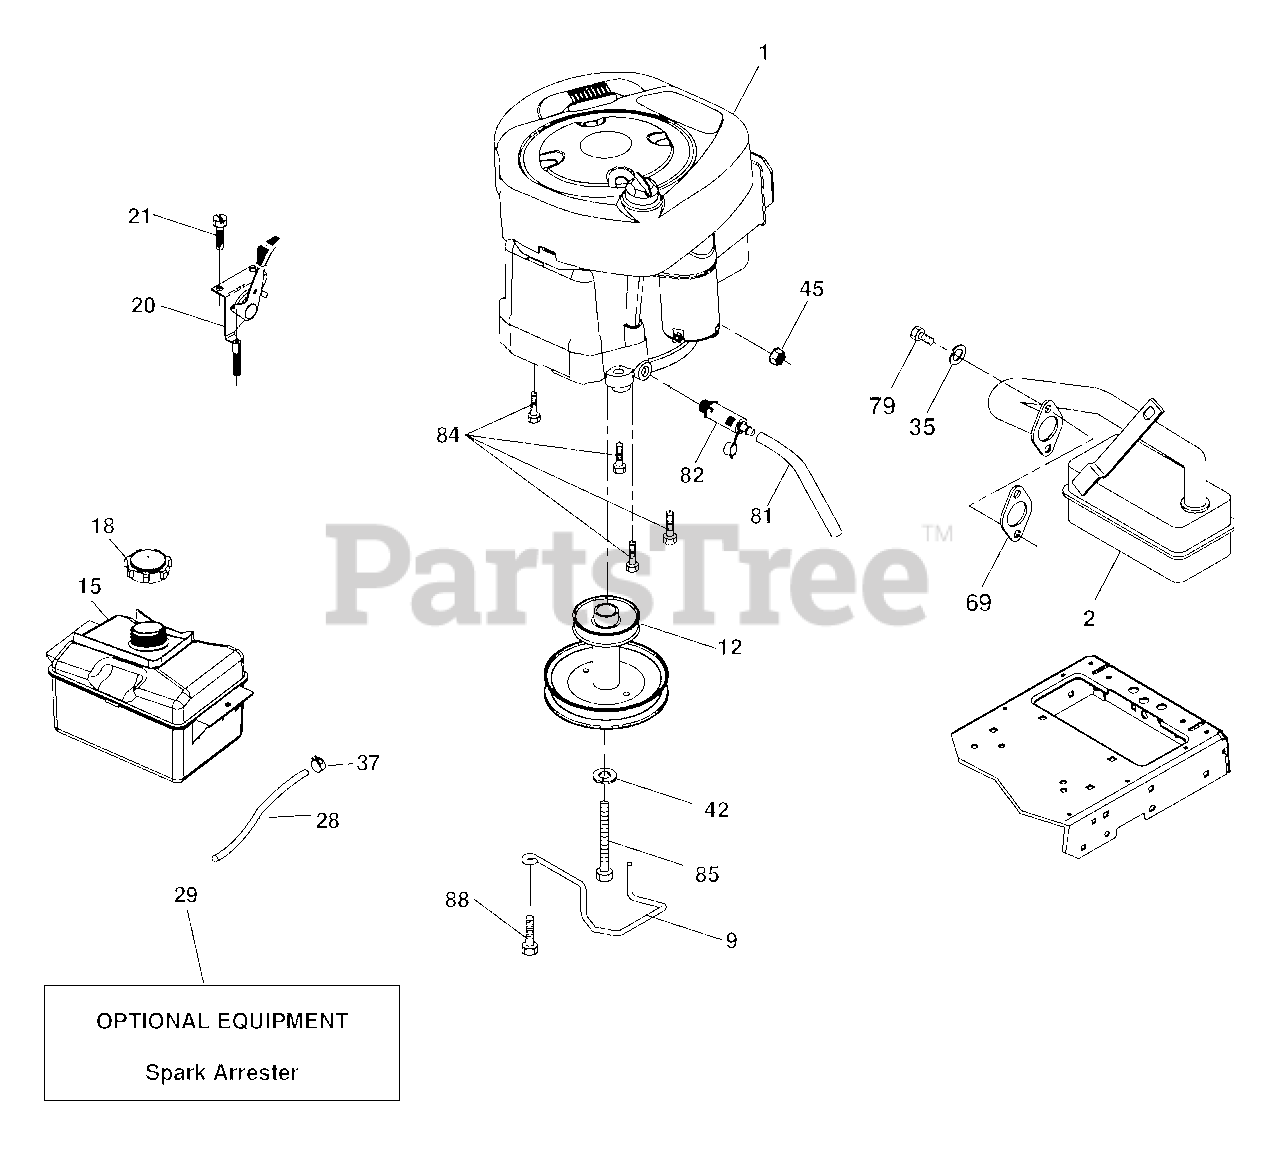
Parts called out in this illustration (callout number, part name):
2	Muffler
9	Keeper Belt Engine
12	Pulley Engine
15	Tank Fuel
18	Cap Asm
20	Control Throttle/Choke
21	Screw 10 x 3/4 Single Lead-Hex
28	Fuel Line
29	Spark Arrester Kit
35	Washer Split
37	Clamp Hose
42	Washer Lock 7/16
45	Nut Keps Hex 1/4-20 unc
69	Gasket
79	Screw Socket Head 5/16-18 x .75
81	Tube Drain Oil Easy
82	Plug Drain Oil
84	Screw 3/8-16 x 1-1/4
85	Bolt Hex 7/16-20 x 4 x Gr. 5-1.5
88	Screw 3/8-16 x 1
